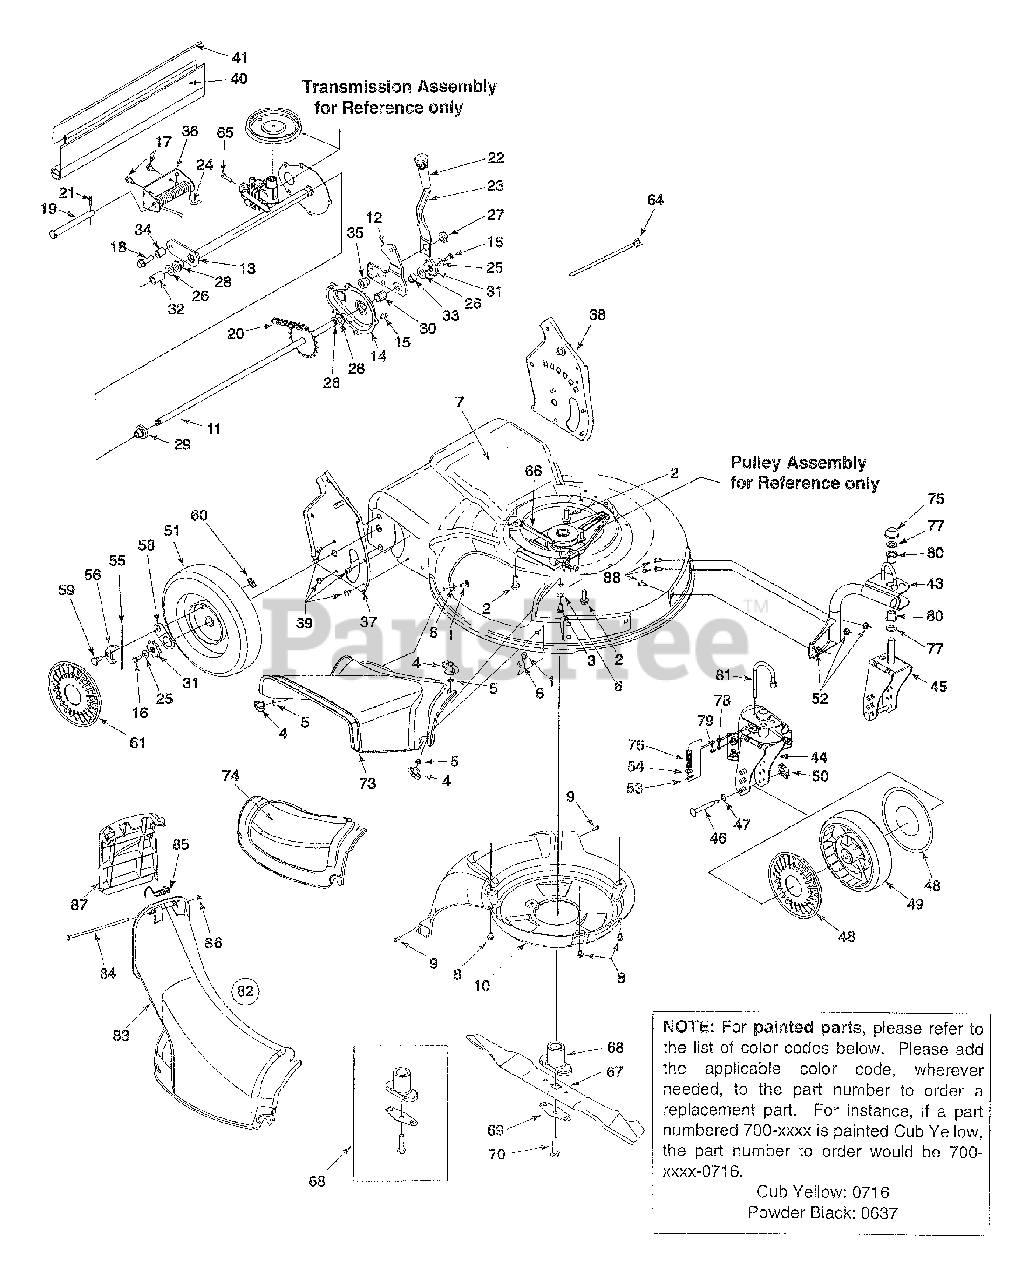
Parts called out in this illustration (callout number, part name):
1	Scr. Carr. 1/4-20 x .62
2	Scr. TT:3/8-18:1.00
3	Carriage Scr. 1/4-20 x .750
4	Wing Nut 1/4-20
5	Nut, Push .25 I.D. x .50 O.D.
6	Wash. Fl. .334 I.D. x .62 x .03
8	Scr. TT 1/4-20 x .375
9	Scr. HL. 1/2-14 x .750
10	Baffle
11	Rear Axle Assembly
16	Cap Screw HH 1/4-20 x .620
17	Scr. AB 1/4-20 x .625
18	Scr. 3/8 116 x .25
19	Clevis Pin .50 Dia. x 4.82 Lg.
20	Chain-Endls. #48 .500P x 24L
21	Cotter Pin .125 O.D. x .75
23	Spring Lever
24	Torsion Spring
25	Bell Wash. .285 x .75 x .082
26	Fl. Wash 508 I.D. 1.000 x .020
27	Nut Shld. .825 Dia. x .165 Lg.
28	Hx. Flg. Brg. .506 I.D. x .590 L.
29	Hx. Flg. Brg. .506 I.D. x .715 L.
30	Hx. Slv. Brg. .504 I.D. x .830 L.
31	Wheel Rachet
32	Spa. .550 I.D. x /750 O.D.
33	Spa. .51 .D. x .70 O.D. x 38 L.
34	Spa. .385 x .624 x .700
35	Shld. Spa. .385 I.D. X .715 Lg.
40	Trail Shield
41	Trail Shield Wire
46	Caster Axle .374 Dia x 2.50"
47	Wave Washer
48	Hub Cap, Beige
49	Wheel 7 x 2 Link
50	Wing Nut 1/4-20
51	Wheel 9 x 2 Link
52	Lock Nut 5/15-18
53	Cotter Pin .072 x .12 Lg.
54	Fl. Wash. .330 x .830 x .060
55	Spring, Ratchet, Plastic
56	Pawl - R.H.
58	Ratchet Pawl Plate
59	Scr. Shld. .340 x .285
60	Top Lock Tab Weld Nut 1/4-20
61	Hub Cap: Radial Spoke Beige
64	Cable Tie
65	Hex Scr. 5/16-18
66	Belt, 3/8" x 39.24"
67	21" Mulching Blade
68	Blade Adapter
69	Blade Bell Suport
70	Hex Bolt 3/8-24 x 2.5" Lg.
73	Side Discharge Chute
74	Mulch Cover
76	Compression Spring
77	Fl. Wash. .5/8 I.D. x 1" O.D.
78	Fl. Wash. .203 x .403 x .040
79	Fitting - Grease
80	Flange Bearing
81	Locking Pin
82	Chute Assembly
83	Discharge Chute
84	Pivot Rod
85	Torsion Spring
87	Chute Door
88	Carr. Bolt 5/16-18 x .62
